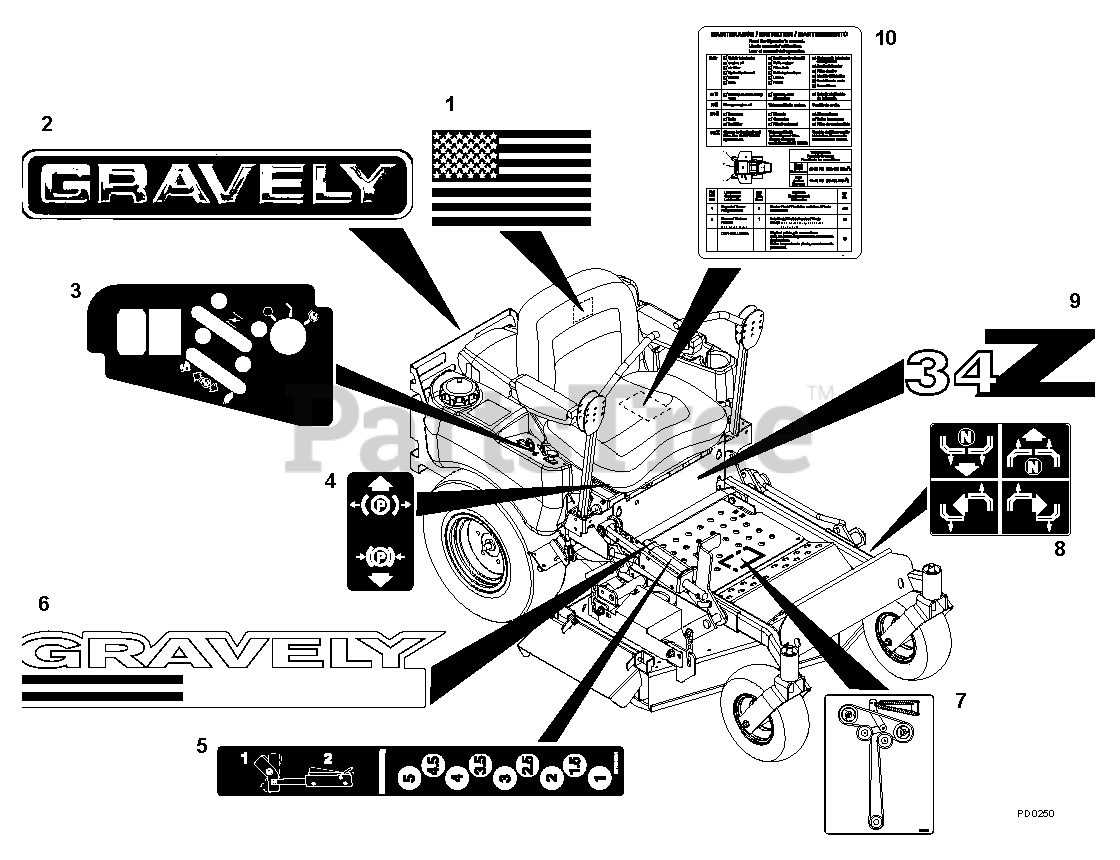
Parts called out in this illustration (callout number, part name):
1	Decal, American Flag
2	Decal, 15" Gravely Logo
3	Decal, Control Panel
4	Decal, Parking Brake Lever
5	Decal, Height of Cut
6	Decal, ZT Hood
7	Decal, Belt Diagram
8	Decal, Instructional Steering
9	Decal, PM 34Z
10	Decal, Maintenance Instructions
